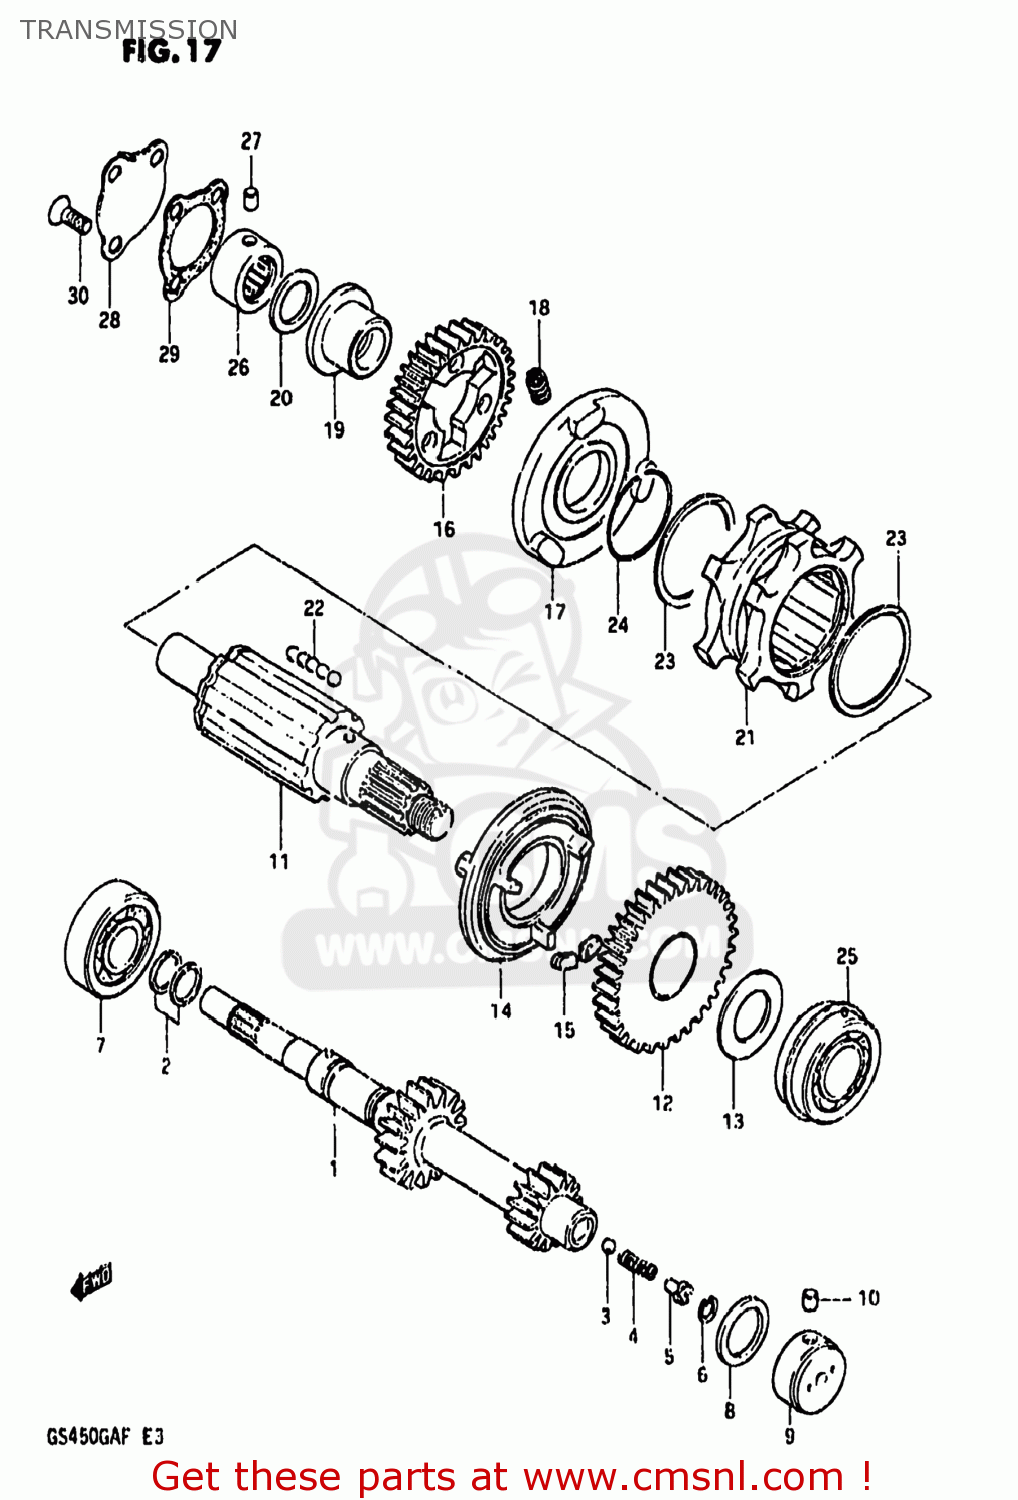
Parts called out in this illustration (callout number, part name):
1	SHAFT,COUNTER
3	BALL
4	SPRING
6	CIRCLIP
7	BEARING
9	ROLLER BEARING (20X34X2
10	PIN
11	SHAFT,DRIVE
12	GEAR,FIRST DRIVEN
13	WASHER
14	BUSHING,FIRST DRIVEN GEAR
15	DAMPER,FIRST DRIVEN
16	GEAR,SECOND DRIVEN
17	DOG PLATE,SECOND DRIVEN
18	SPRING
19	BUSHING
21	SLIDING DOG
22	BALL
23	CIRCLIP
24	CIRCLIP
25	BALL BEARING 25X52X21
26	BEARING(20X34X16)
27	PIN
28	PLATE,COUNTERSHAFT BEARING
29	GASKET,DRIVESHAFT BEARING RIGHT,TOP
30	SCREW
